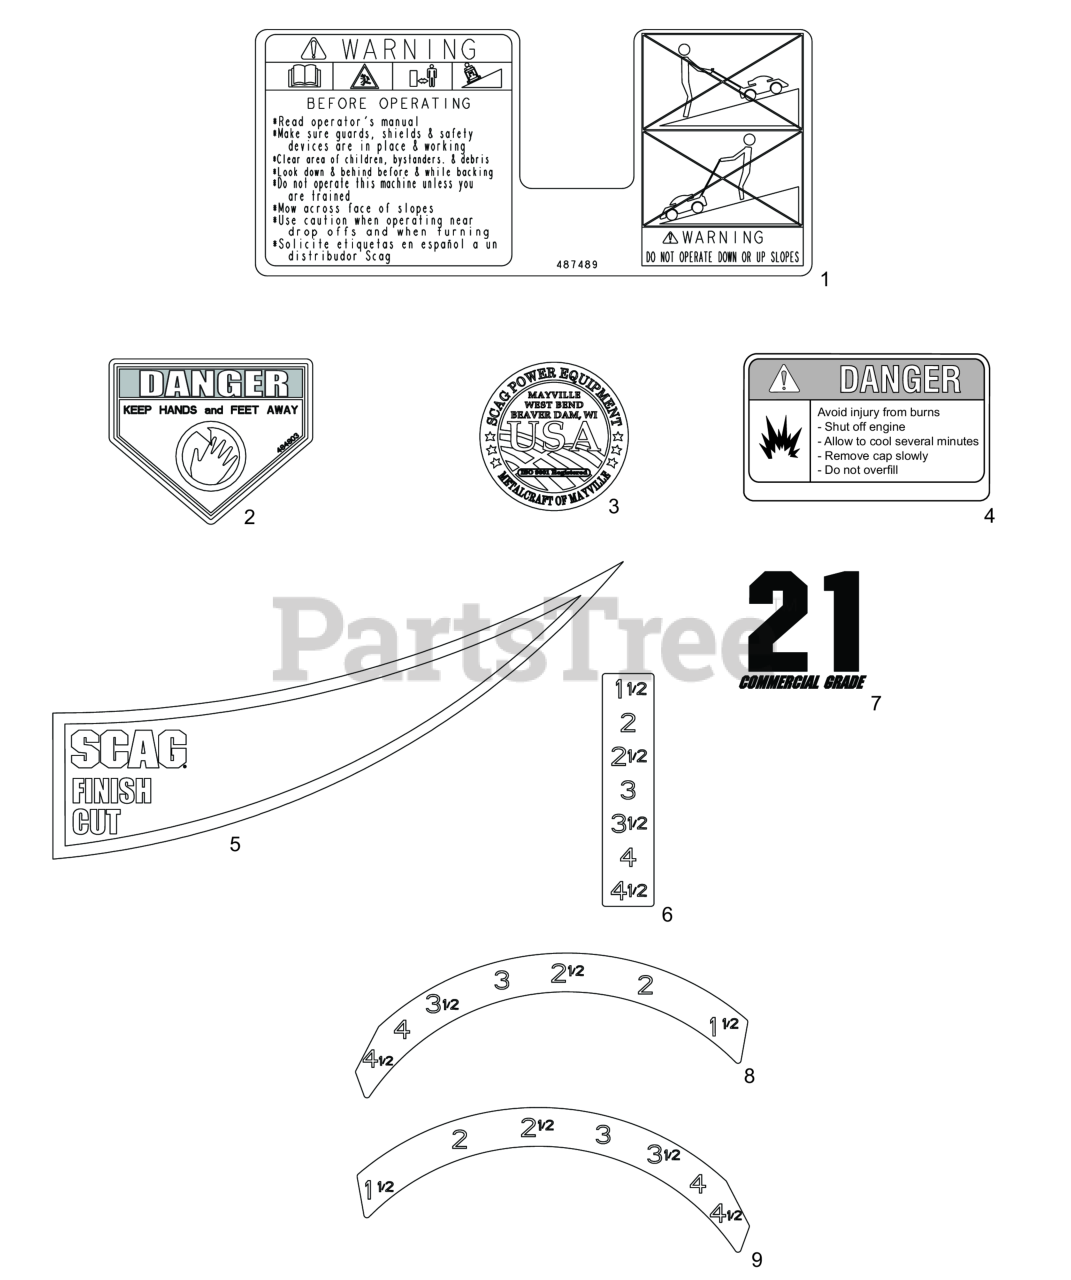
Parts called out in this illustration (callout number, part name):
1	Decal, Warning - SFC21
2	Decal, Danger - Cut Finger
3	Decal, Metalcraft - USA
4	Decal, Fuel Tank
5	Decal, SFC-21
6	Decal, Cut Height - Front
7	Decal, 21 Commercial Grade
8	Decal, Cut Height - Rear, LH
9	Decal, Cut Height - Rear, RH
